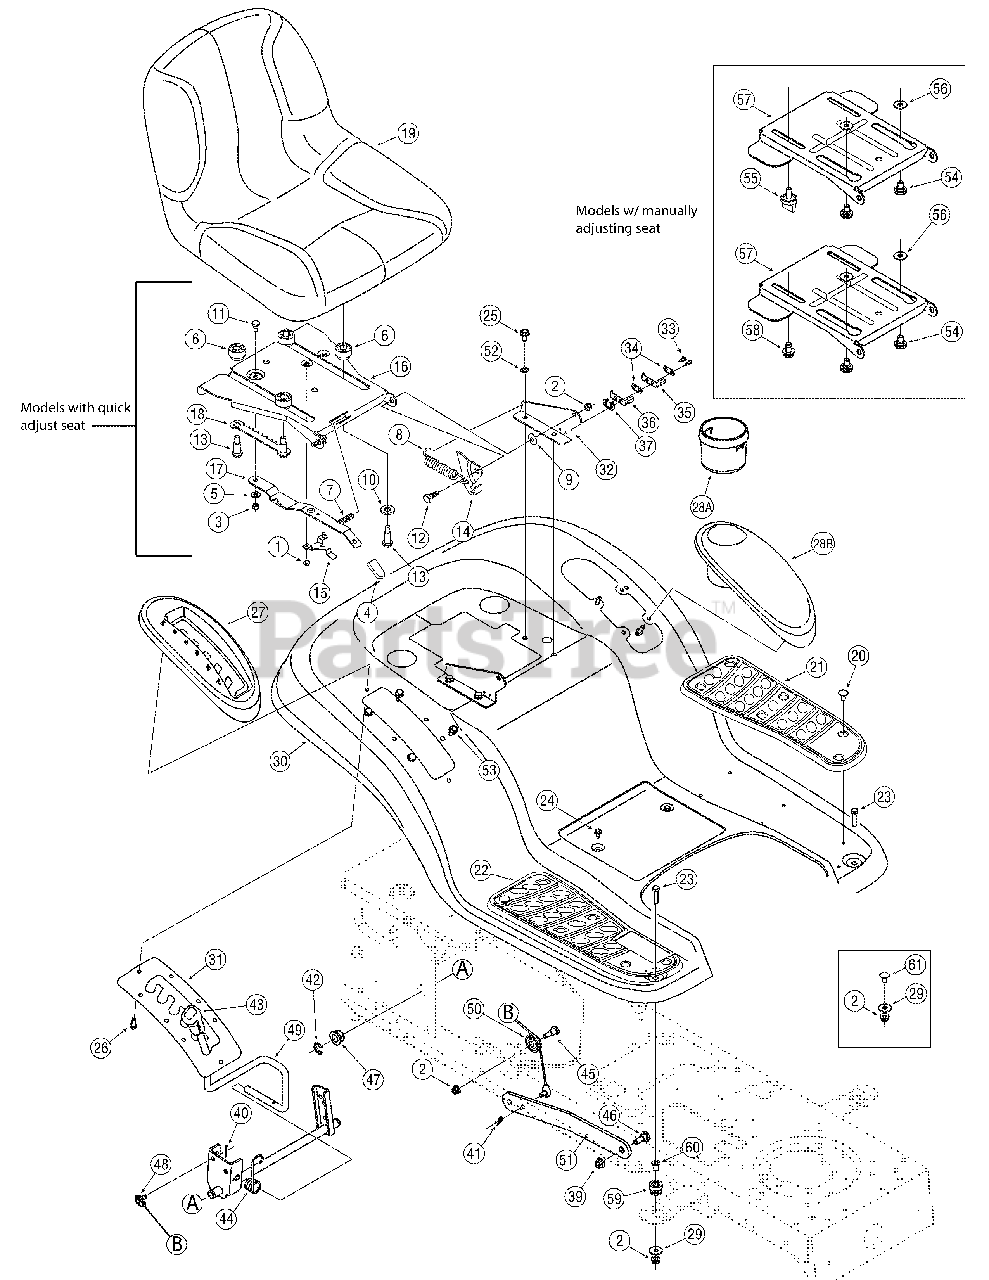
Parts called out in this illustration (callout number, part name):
1	Screw, #10-16 x.375
2	Nut, Flange Lock, 5/16-18, GrF
3	Nut, Flange Lock, 1/4-20
4	Seat Adjuster Grip
5	Washer, Flat .344 x .62 .033
6	Spacer
7	Compression Spring,.41 x 1.5
8	Spring, Extension,.84 Dia. x 4.6
9	Wash, Flat, .340 x .688 x .065
10	Wash, Flat,.531x 1.062 x.134
11	Screw, Shld, .340 x.285, 1/4-20
12	Screw, Shoulder,.437 x.268
13	Screw, Should,.50 x.925, 3/8-16
14	Seat Bracket, Lift
15	Seat Stop
18	Seat Adjustment Selector
19	Low Back Seat
19	Medium Back Seat
19	High Back Seat
20	Ratchet Clip
21	LH Foot Pad (shown)
21	LH Foot Pad, Rubber
22	RH Foot Pad (shown)
22	RH Foot Pad, Rubber
23	Hex Screw, 5/16-18 x 1.25
24	Screw, 1/4-20, 0.500
25	Screw, 5/16-18, 0.625
26	Screw, 1/4-15, 0.750
27	Cover, Lift Lever
29	Washer, Flat,.344 x 1.0 x.063
33	Screw, #8-18 x.50
34	Plate, Insulator
35	Spring Switch, Outer
36	Spring Switch, Inner
37	Plate, Insulator Boss
40	Pin, Cotter,.072 Dia. x 1.13
41	Pin, Cotter, 3/32, 1.0
42	Ring, E Type,.625 Dia.
43	Grip, Handle, 1/2
44	Spring, Torsion
45	Bolt, Shldr, 3/8-16 .496 x 2.50
46	Scr.,Shldr, .625 x.165,(42" Deck)
46	Screw, Shld,.50 x.27, (46" Deck)
47	Bearing, Hex Flange
48	Cable, Lift, 16.16
49	Handle, Lift
50	Pulley, Roller
52	Lock Washer, 5/16
53	Scr5/16-18 x.750 (10-Style)
53	Screw, 5/16-18, 0.625 (4-Style)
54	Shoulder Screw
55	Knob, 3/8-16
56	Flat Washer, .406 x .875 x .059
58	Hex Head Flange Screw, 3/8-16
59	Grommet, .4375 x .750
60	Flanged Spacer
61	Carriage Bolt, 5/16-18 x .750
